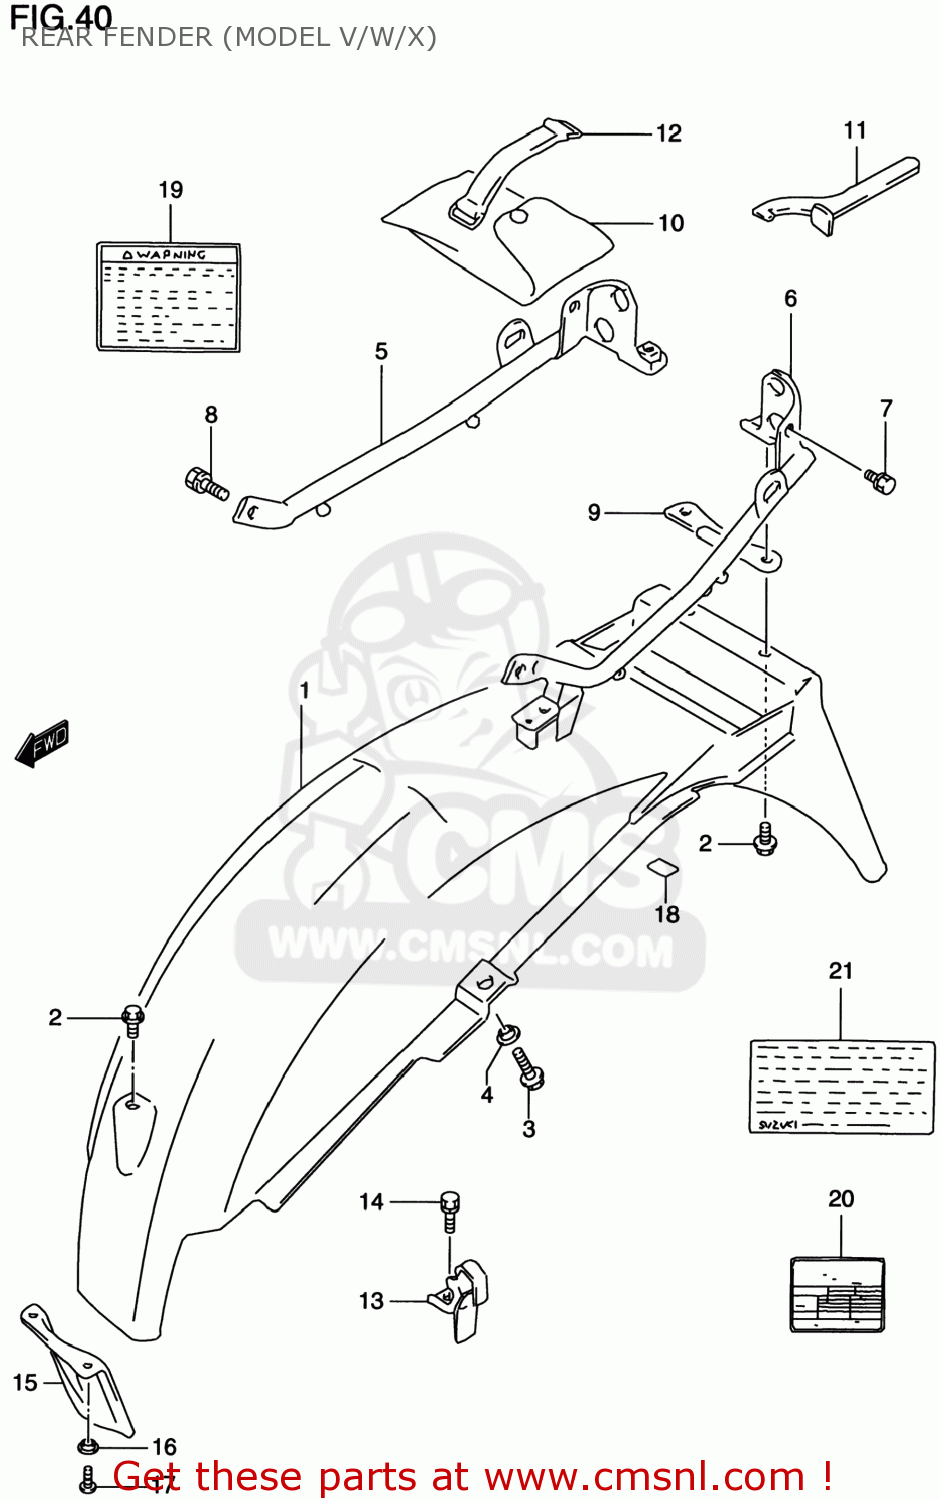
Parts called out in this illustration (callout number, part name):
1	BODY,REAR FENDER
2	BOLT
3	BOLT
4	WASHER
5	BRACE,RR FENDER,R
6	BRACE,RR FENDER,L
7	BOLT
8	BOLT
9	PLATE,TOOL HOLDER
10	TOOL ASSY
11	CLAMP
12	BAND
13	HOLDER,HELMET
14	BOLT
15	GUARD,RR UNIT MUD
16	WASHER
17	SCREW
18	TAPE,RR FENDER
19	LABEL,WARNING SAFETY
20	LABEL,TIRE AIR PRESSURE
21	LABEL (MANUAL NOTICE)
22	LABEL (VACUUM HOSE ROUTING)
23	MANUAL, OWNER'S
